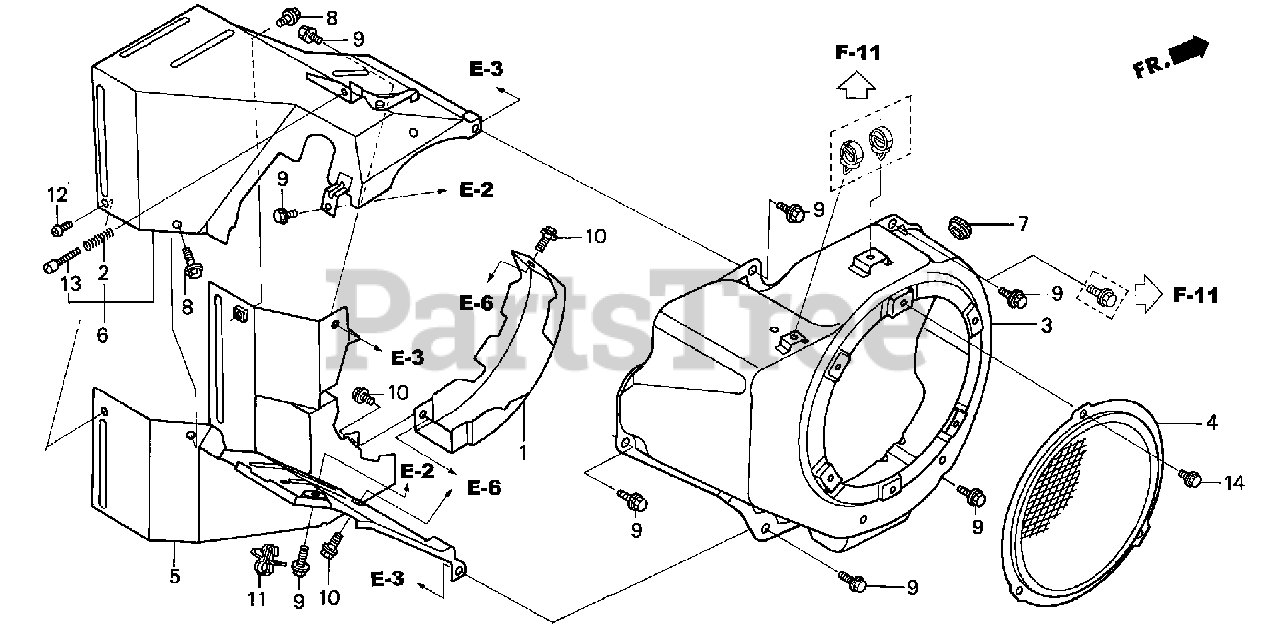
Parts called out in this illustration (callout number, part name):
1	SCROLL, GENERATOR FAN
2	SPRING, CONTROL ADJUSTING
3	COVER, FAN
4	PROTECTOR, FAN COVER *R8* (BRIGHT RED)
5	SHROUD (LOWER)
6	SHROUD ASSY. (UPPER)
7	GROMMET, DRAIN HOLE
8	BOLT, FLANGE (6X8)
9	BOLT, FLANGE (6X12) (CT200)
10	BOLT, FLANGE (5X10)
11	CLIP, WIRE HARNESS (6MM) (WHITE)
12	SCREW, PAN (5X8)
13	SCREW, PAN (5X32)
14	BOLT, FLANGE (6X8)
